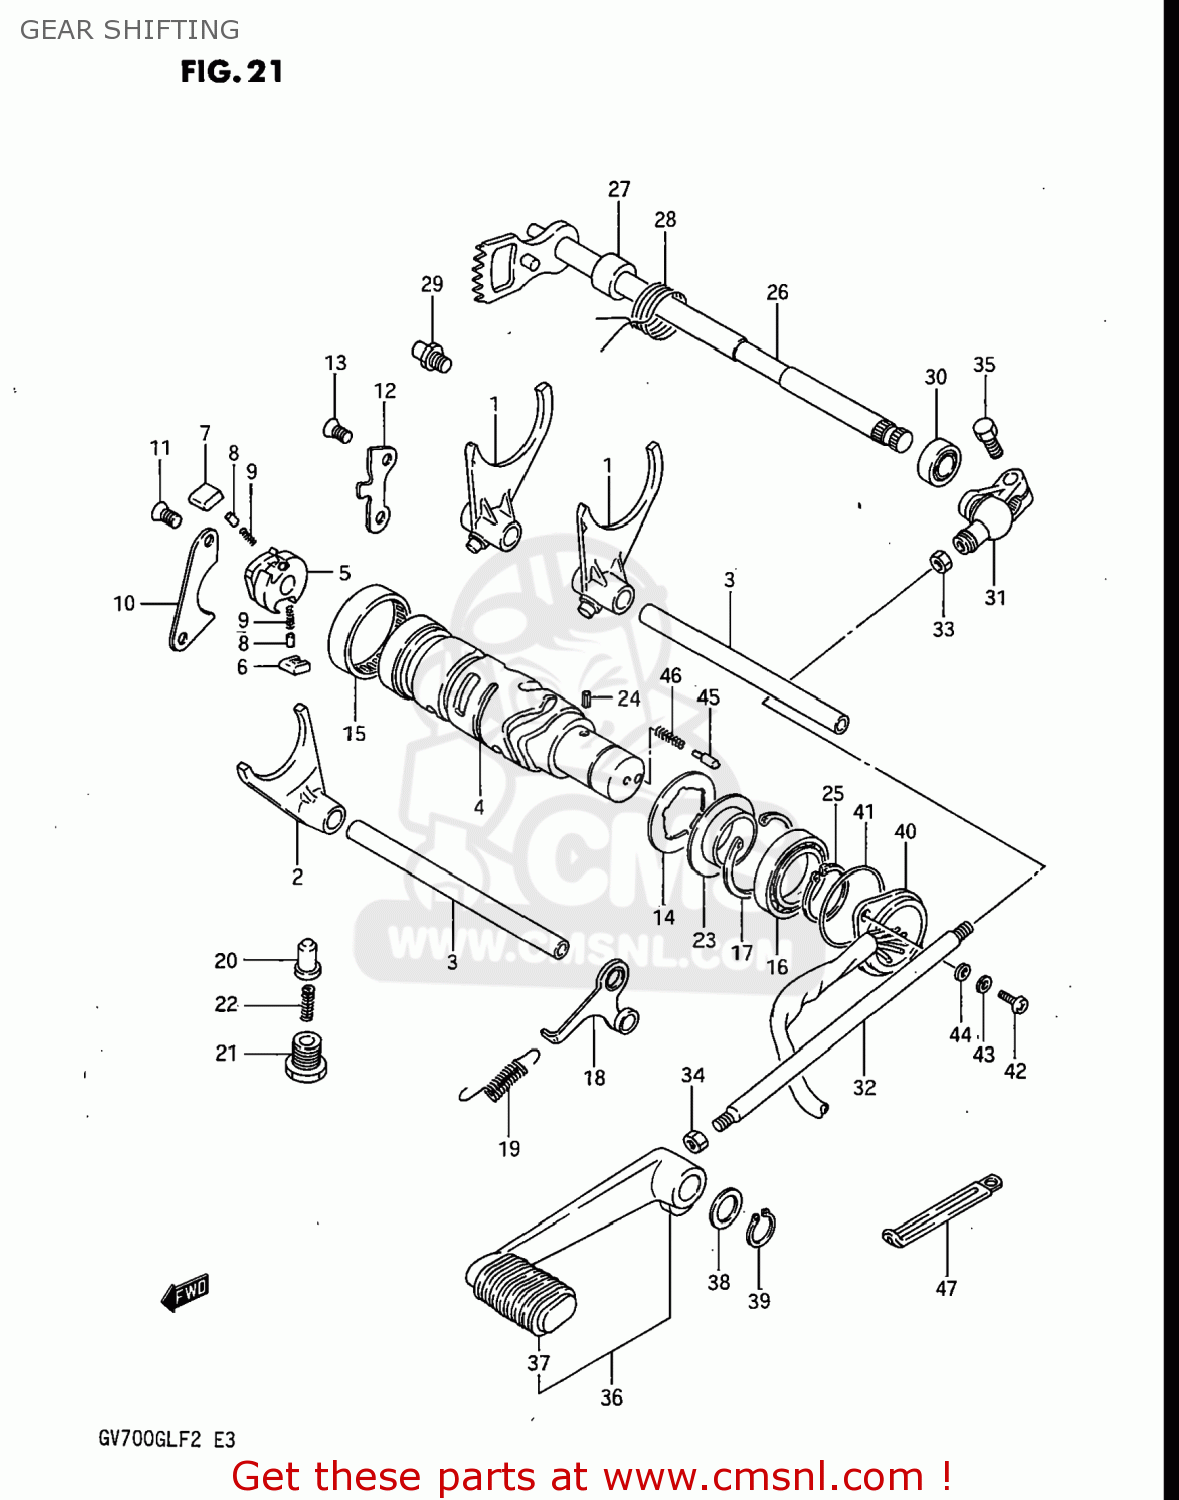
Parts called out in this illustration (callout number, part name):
1	FORK,GEAR SHIFT NO.1
2	FORK,GEAR SHIFT NO.3
3	SHAFT,GEAR SHIFT FORK
4	CAM,GEAR SHIFT
5	GEAR,GEARSHIFT CAM DRIVE
6	PAWL,GEAR SHIFT NO.1
7	PAWL,GEAR SHIFT NO.2
8	PIN(5X8)
9	SPRING
10	LIFTER, PAWL
11	SCREW
12	GUIDE,GEAR SHIFTING CABLE
13	SCREW
14	WASHER,LOCK
15	BEARING(43X49X12)
16	BALL BEARING
17	CIRCLIP,42MM
18	STOPPER,GEAR SHIFTING
19	SPRING
20	STOPPER,GEAR SHIFTING
21	HOLDER,GEAR SHIFT CAM STOP SPR
22	SPRING
23	PLATE,STOPPER
24	PIN 4X6
25	CIRCLIP,25MM
26	SHAFT,GEAR SHIFT
27	SPACER(12X20X15.3)
28	SPRING
29	STOPPER,GEAR SHIFT CAM
30	OIL SEAL
31	ARM,GEAR SHIFT SHAFT
32	ROD,GEAR SHIFT LINK
33	NUT
34	NUT
35	BOLT
36	LEVER ASSEMBLY,GEAR SHIFTING
37	RUBBER,GEAR SHIFT PEDAL
38	WASHER(12.5X20X1)
39	CIRCLIP
40	TERMINAL BASE,NEUTRAL
41	O RING(D:2.4,ID:36.5)
42	SCREW(5X14)
43	LOCK WASHER
44	WASHER
45	PIN(5X15.5)
46	SPRING
47	CLAMP
